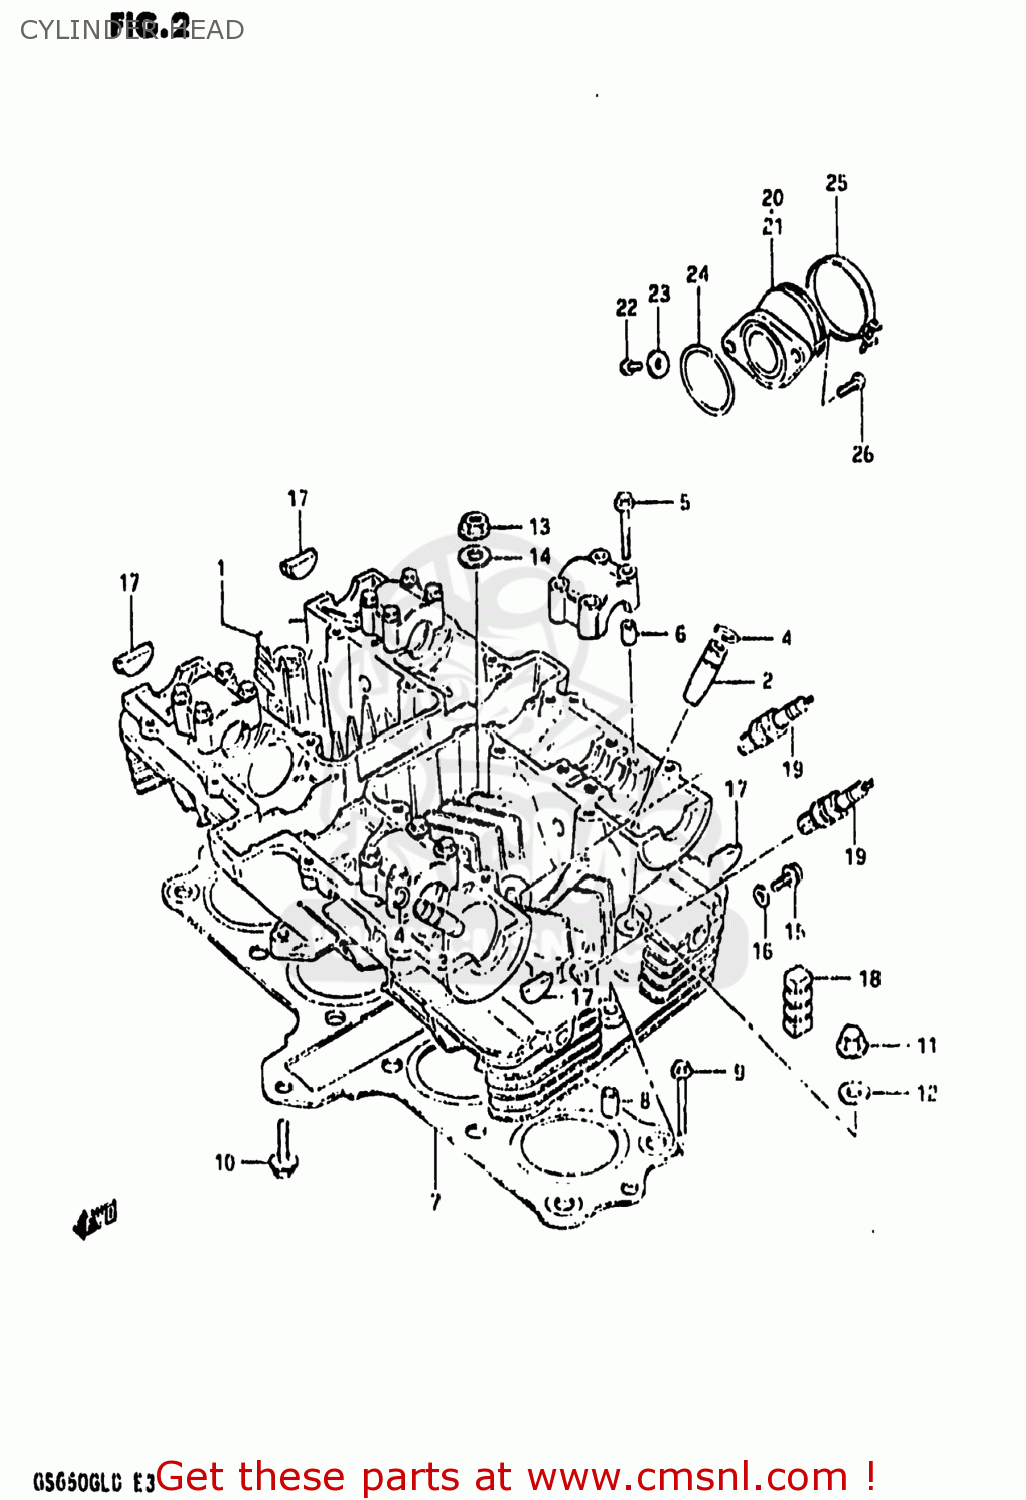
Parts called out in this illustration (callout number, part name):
1	HEAD,CYLINDER
2	GUIDE,INTAKE VALVE
3	GUIDE,EXHAUST VALVE
4	RING,SNAP
5	BOLT(6X39)
6	PIN(6.2X8X11)
7	GASKET,CYLINDER HEAD (MCA)
8	PIN
9	BOLT (6X45)
10	BOLT 6X30
11	NUT
12	GASKET (NAS)
13	NUT
14	WASHER(8.5X19X2.3)
15	BOLT 6X12
16	GASKET (NAS)
17	PLUG
18	PAD,CYLINDER
19	SPARK PLUG D8EA
20	PIPE,INTAKE,R
21	PIPE,INTAKE,L
22	BOLT
23	WASHER,5MM
24	O-RING
25	CLAMP
26	SCREW
